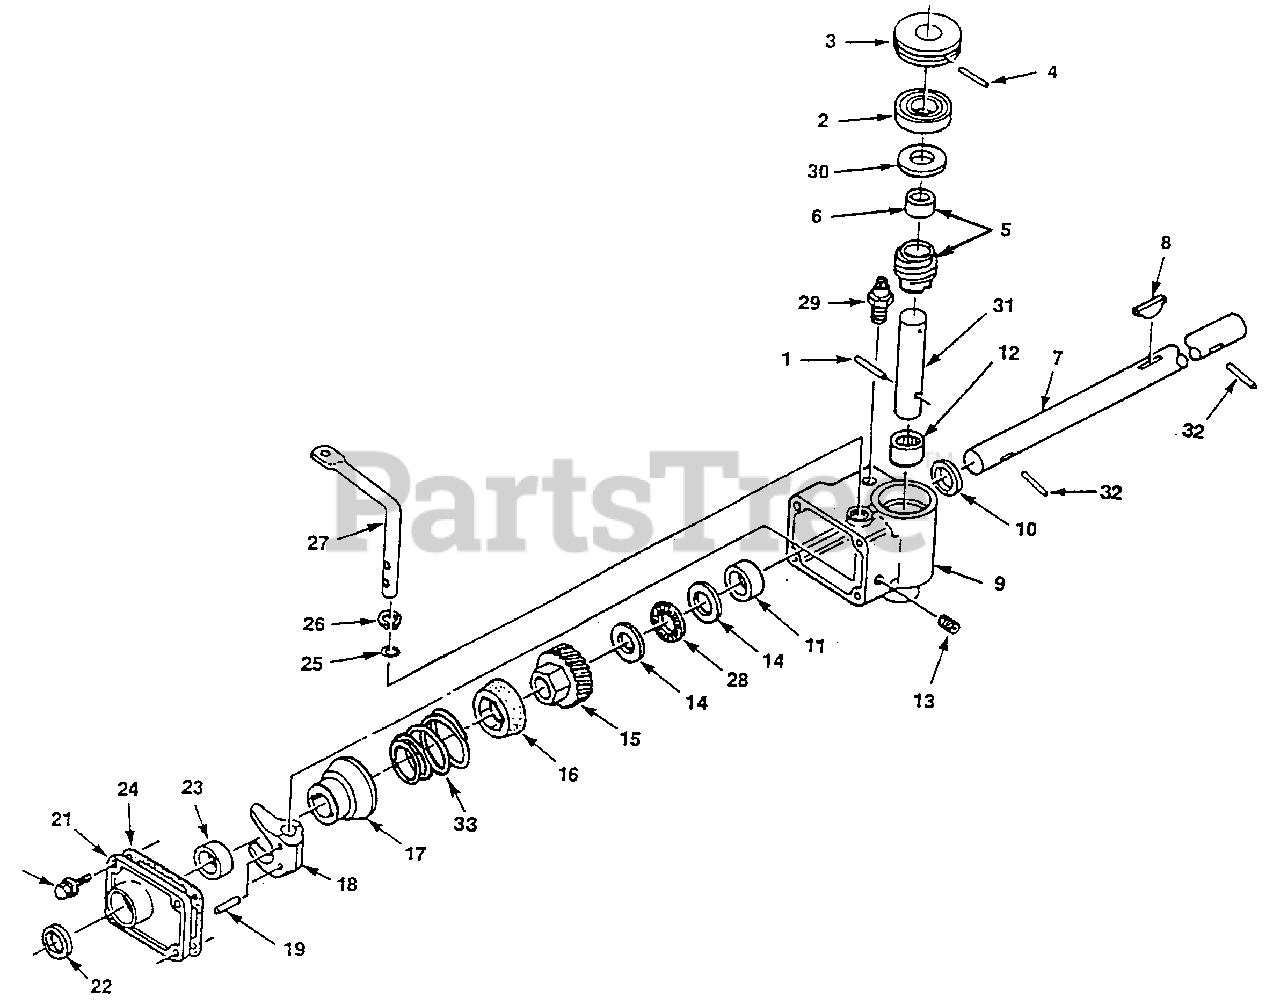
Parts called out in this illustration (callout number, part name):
1	Pin - Roll 3/16 x 7/8
2	Bearing - Bail
3	Pulley - Gear box
4	Pin - Roll 3/32 x 1 1/4"
5	WORM & SPACER
6	SPACER - Worm
7	SHAFT- Drive
9	HOUSING - Gear box
11	BUSHING - Sleeve
12	BEARING - Needle
13	PLUG - Pipe
14	RACE - Thrust
15	GEAR - Helical
16	CONE - Friction
17	DRUM - Clutch
18	FORK - Shift
19	PIN - Groove
20	SCREW - 1/4-20 x 7/8"
21	COVER - Gear Box
23	BUSHING - Sleeve
24	GASKET - Cover
26	TRU-ARC RING
27	LEVER - Shift
28	BEARING - Needle
31	WORM - Shaft
32	PIN - Roll 1/8" x 7/8"
33	SPRING - Clutch
